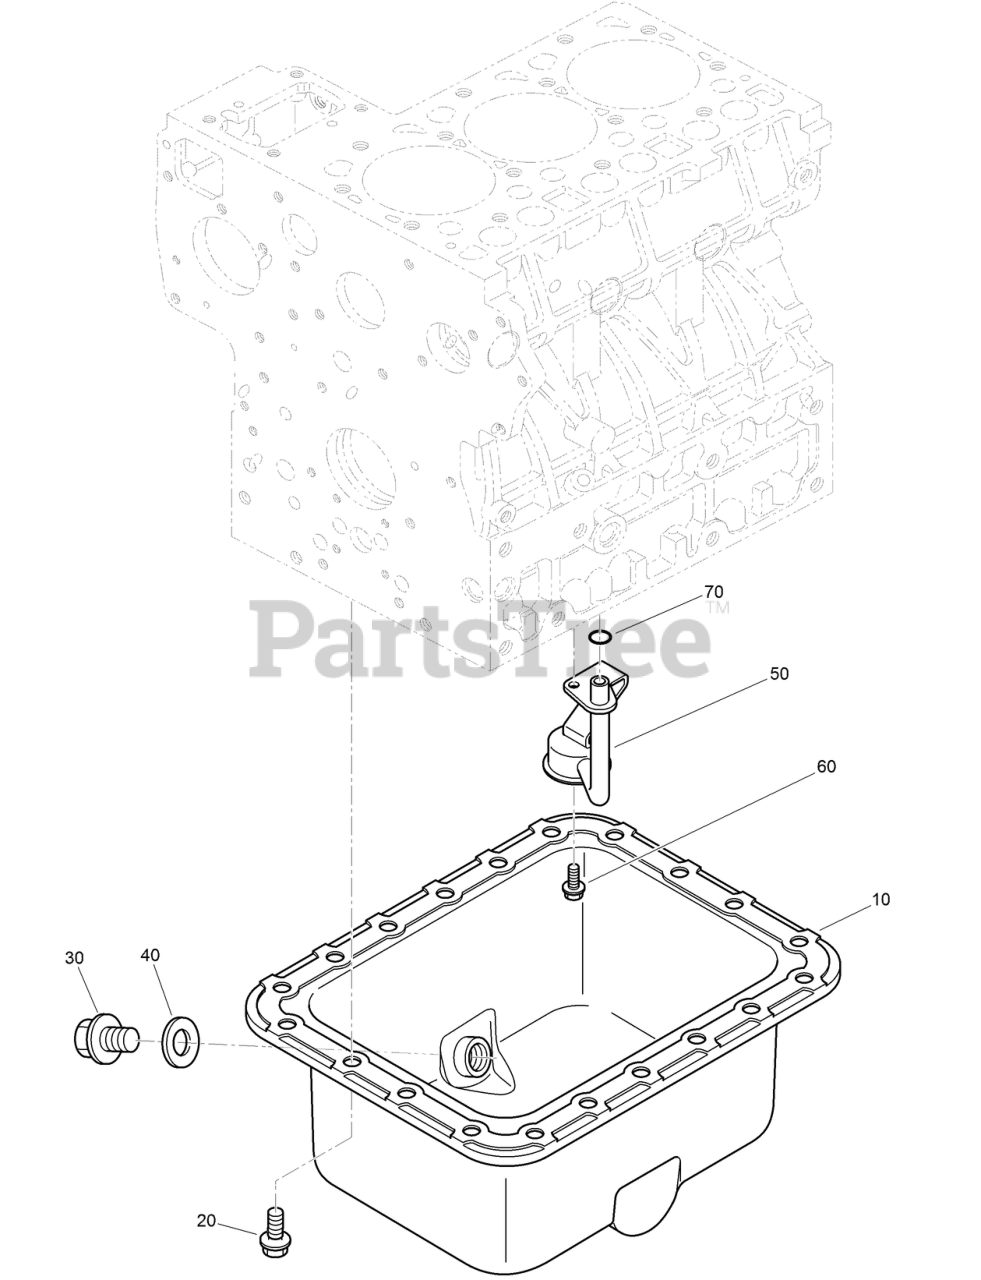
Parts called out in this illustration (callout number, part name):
10	PAN-OIL
20	BOLT-FLANGE
30	PLUG-DRAIN
40	WASHER-SEAL
50	FILTER-OIL
60	BOLT-FLANGE
70	O-RING
